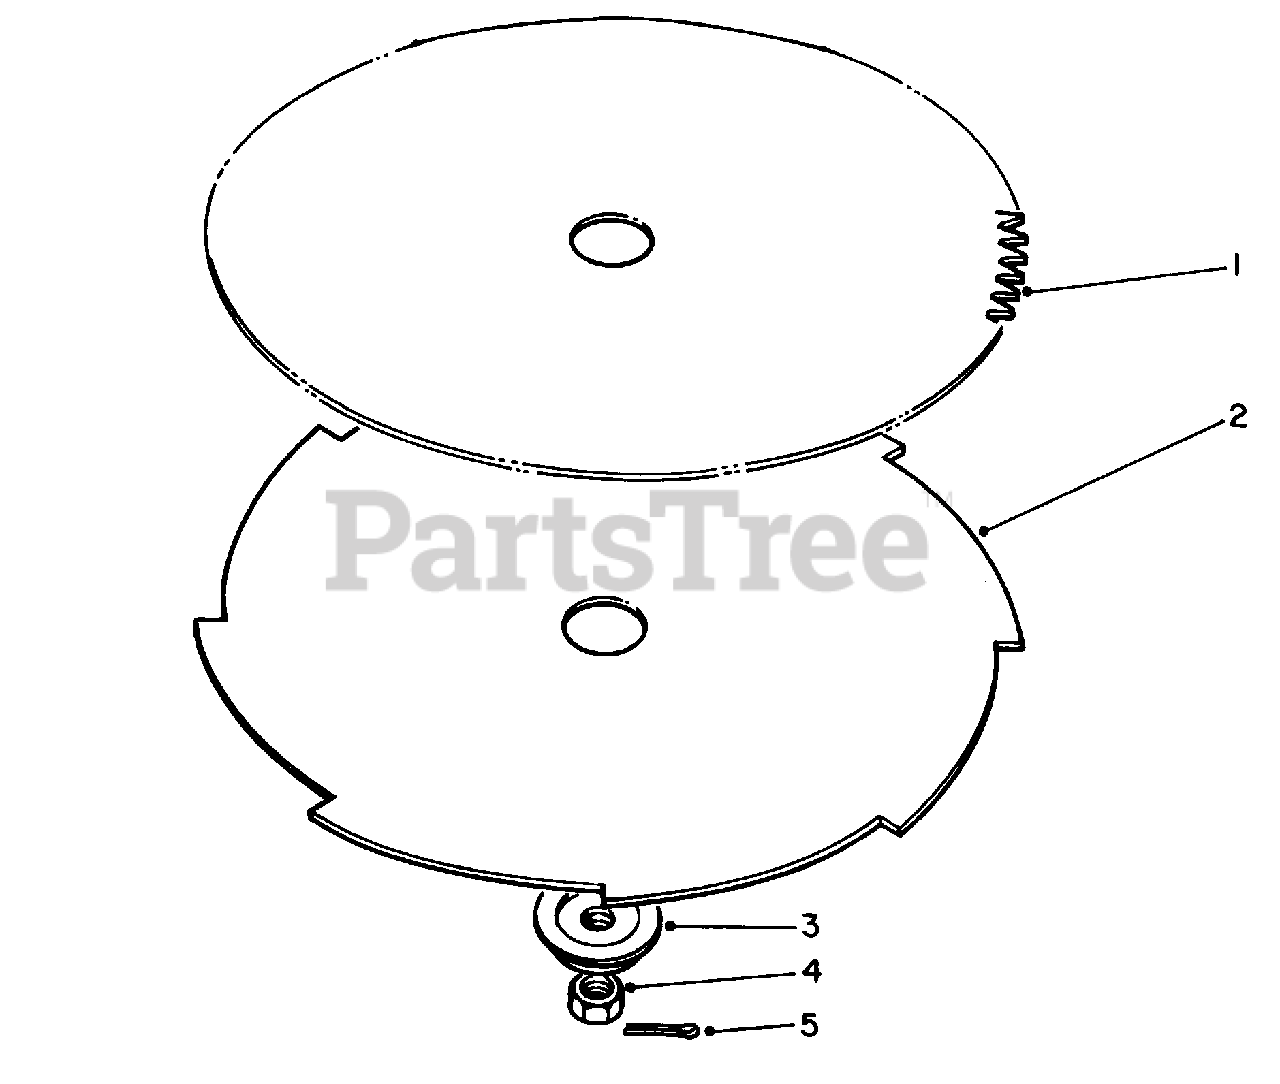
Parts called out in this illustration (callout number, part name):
1	SAW BLD PKG(8", 80T)
2	BRUSH BLD PKG(8",8T)
3	Adapter-Blade
5	1/16 X 1 LG COTTER PIN
